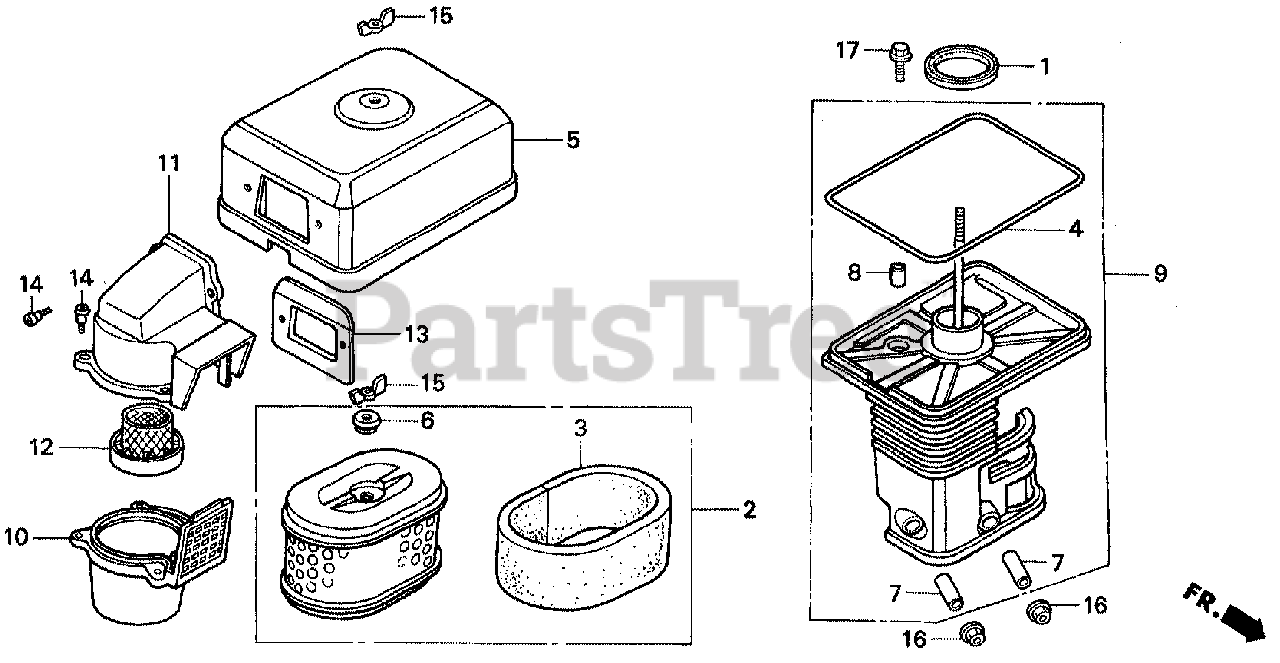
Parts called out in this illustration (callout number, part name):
1	GASKET, ELBOW
2	ELEMENT, AIR CLEANER (DUAL)
3	FILTER (OUTER)
4	GASKET, AIR CLEANER COVER
5	COVER, AIR CLEANER (DUAL)
6	GROMMET, AIR CLEANER
7	COLLAR, AIR CLEANER
8	COLLAR B, AIR CLEANER
9	ELBOW, AIR CLEANER
10	CASE, PRE AIR CLEANER
11	CAP, PRE AIR CLEANER
12	GUIDE, PRE AIR CLEANER
13	PLATE, PRE AIR CLEANER
14	BOLT, MUDGUARD
15	WINGNUT, TOOL BOX SETTING
16	NUT, FLANGE (6MM)
17	BOLT, FLANGE (6X20)
